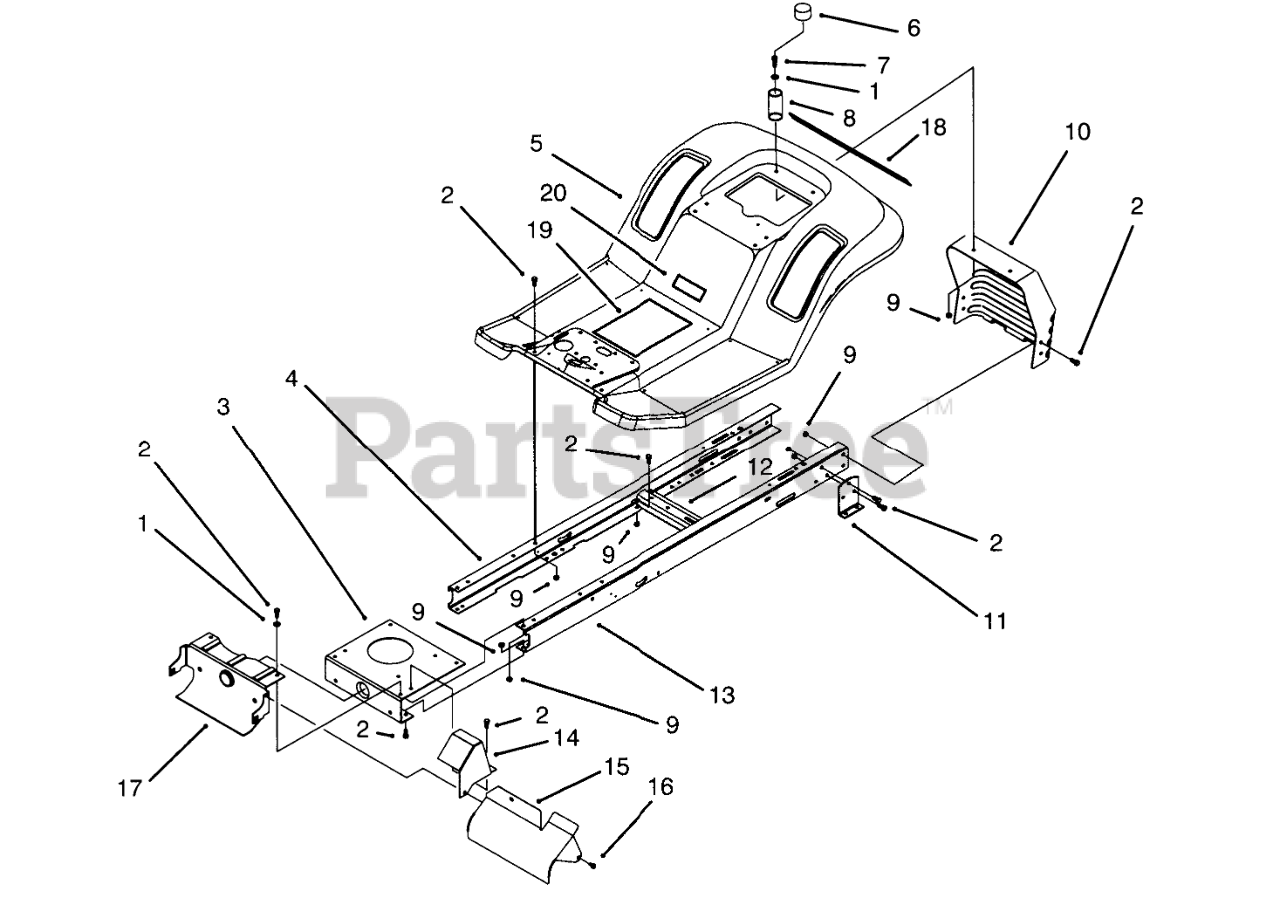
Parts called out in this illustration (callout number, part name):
1	WASHER-PLAIN
2	SCREW-HH
3	Plate-Engine Mount
4	Frame-Rail R.H.
5	BODY-REAR
6	CAP-PROTECTOR
7	SCREW-HH
8	SPRING-COMPRESSION
9	NUT-LOCK, NI
10	Panel-Rear Hitch
11	Bracket-Transaxle
12	Bracket-Idle Pivot
13	Frame-Rail L.H.
14	Shield-Exhaust Pipe
15	Shield-Muffler
16	SCREW-HWHTF
17	Support-FrontAxle
18	DECAL - REAR BODY
19	Decal-Instruction
20	Decal-Made In USA
